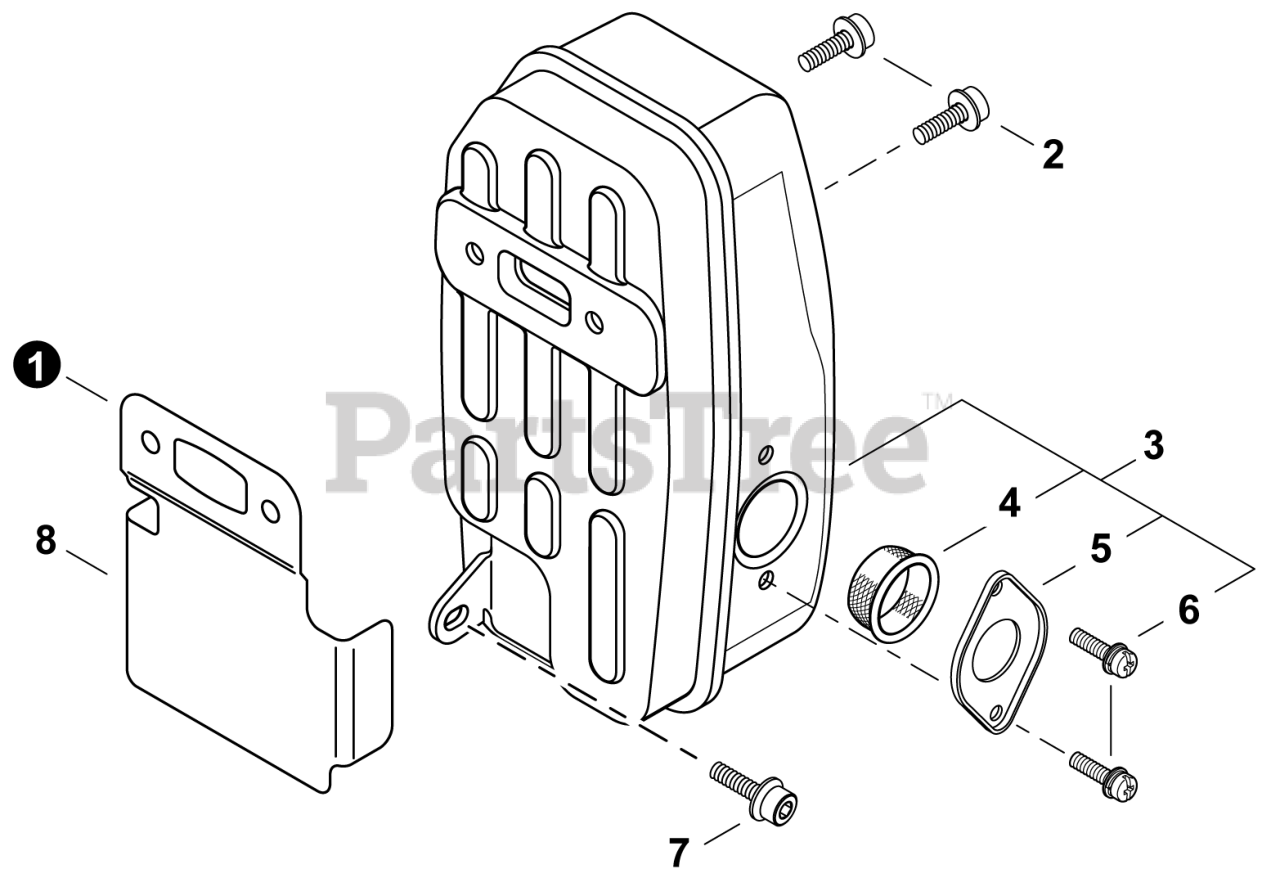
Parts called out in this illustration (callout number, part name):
1	HEAT SHIELD, EXHAUST
2	BOLT, FLANGE 6x20
3	MUFFLER ASSY
4	SCREEN, SPARK ARRESTER
5	GUIDE, EXHAUST
6	SCREW 4x10
7	BOLT 5x14
8	GASKET KIT
